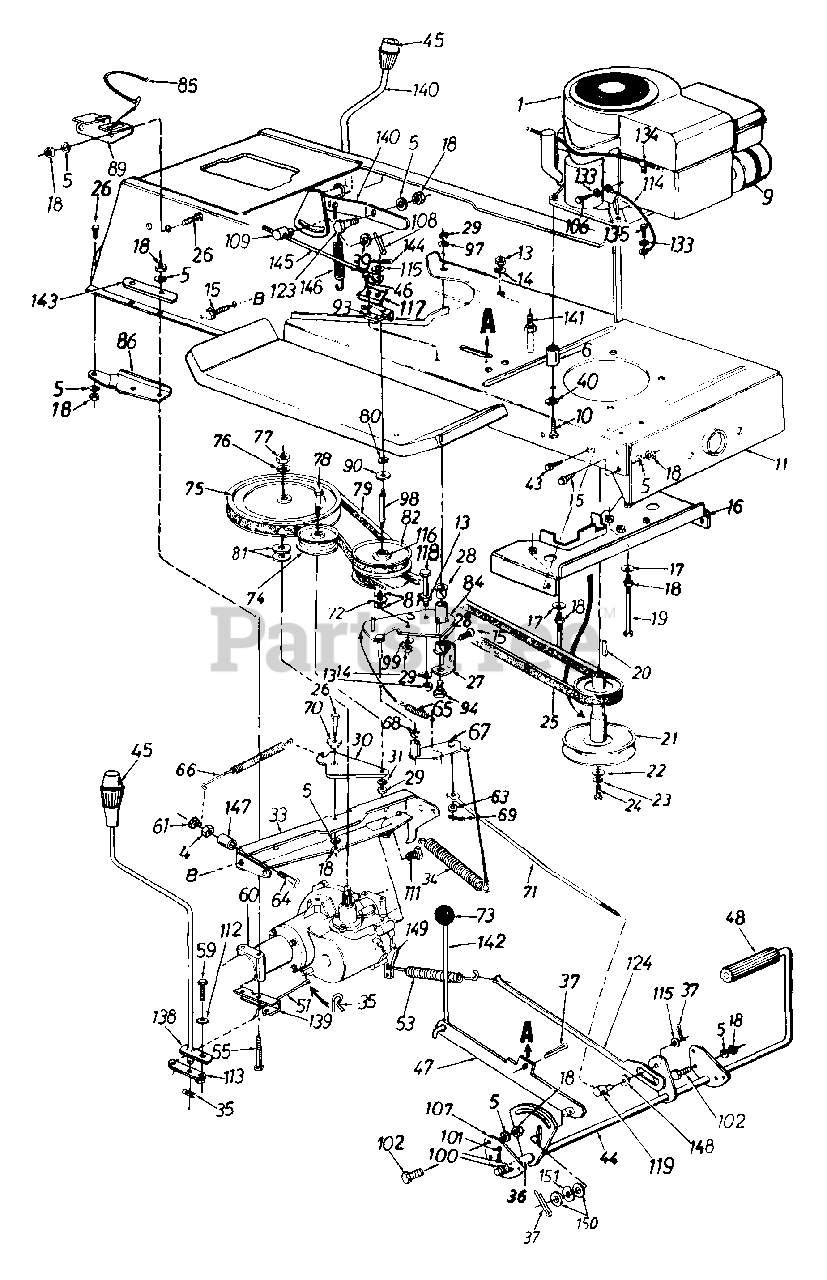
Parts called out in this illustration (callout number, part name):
1	Engine
4	Hex Nut 5/16-24 Thd.
5	L-Wash. 5 16" I.D.
6	Spacer
9	Muffler
10	Hex L-Wash. Tap Scr. 3/8-16 Thd.
11	Lower Frame Ass'y.
13	Hex Nut 1/4-20 Thd.
14	L-Wash. 1/4" I.D.
15	Hex Wash. TT-Tap Scr. 5/16-18 x .62" Lg.
16	Belt Guard Brkt. Ass'y.
17	Bell-Wash..345" I.D. x .88"
18	Hex Nut 5/16-18 Thd.
19	Hex Bolt 5 16-18 x 4.0"
20	Sq. Key 1/4" x 1/4" x 2.00"
21	Engine Pulley
22	Fl-Wash. 7/16" I.D. x 1.25"
23	L-Wash. 1/16" I.D.
24	Hex Bolt 7/16-20 x 1.50" Lg.
25	Variable-Speed Belt
26	Hex Bolt 5/16-18 x .75" Lg.
27	Bearing Shaft Bracket
28	Flanged Nyliner Brg..63" I.D. x .6" Lg.
29	Hex Nut 3/8-24 Thd.
30	Idler Bracket
31	L-Wash. 3/8" I.D.
33	Transaxle Support Brkt.
34	Ext. Spring .94" O.D. x 7.58"
35	Inter. Cotter Pin
36	Spacer .63" I.D.
37	Cotter Pin 1/8" Dia. x 1.25" Lg.
39	Fl-Wash..51" I.D. x .75"
40	Fl-Wash..406" I.D. x 1.25"
43	Hex Wash. Hd. S-Tap Scr. 1/4-20 x .50" Lg.
44	Clutch/Brake Pedal Ass'y.
45	Shift Knob
46	Truss Mach. B-lap Scr. #10 x .5" Lg,
47	Parking Brake Lockout Brkt. Ass'y.
48	Foot Pad
51	Shift Lever Rod
53	Ext. Spring 3.6"
55	Hex Bolt 5/16-18 x 3.25"
59	Hex Bolt 1/4-28 x .62" Lg.
60	Transaxle Complete
61	Hex L-Nut 1/4-20 Thd.
63	Fl-Wash..34" I.D. x .68" O.D.
64	Hex Wash. TT-Tap Scr. 1/4-20 x 1.75"
65	Ext. Spring 2.59" Lg.
66	Ext. Spring .5" O.D. x 4.35"
68	Flanged Bearing
69	Cotter Pin 3/32" Dia.
70	Shoulder Spacer .27" Lg.
71	Speed Control Link
72	Truss Bearing .56 Dia. x 1.25"
73	Ball Knob
74	Fl-Idler Pulley 3.25" x .75"
75	"V"-Pulley
76	Bell-Wash..567" I.D. x 1.125"
77	Hex Jam Nut 9/16-18 Thd.
78	Hex Bolt 3/8-24 x 1.75" Lg.
79	Variable Speed Belt
80	Snap Ring .56" Dia.
81	Fl-Wash..56" I.D. x 1.0" O.D.
82	Variable Speed Pulley Ass'y. 5" O.D.
90	Teflon Washer .565" I.D.
93	Safety Switch (Clutch)
94	Shld. Bolt 3/8-24 x 3.12" Lg.
97	Bell-Wash..38" I.D. x .88"
98	Shaft
99	Bell-Wash..39" I.D. x 1.12"
100	Fl-Wash..64" I.D. x .94"
101	Cotter Pin 1/8" Dia. x 1.25"
102	Hex Wash. Hd. Scr. 5/16-18 x .62" Lg.
106	Truss Mach. Scr. 5/16-18 x .75" Lg.
109	Ferrule
111	Hex Wash. Tap Scr.
112	Bell-Wash..265" I.D. x .75"
113	Shift Lever Link Ass'y.
114	Ground Wire 7.5" Lg.
115	Fl-Wash..385" I.D. x .62"
116	Needle Brgs.
117	Switch Plate
118	Hex Bolt 1/4-20 x 3.25" Lg.
119	Ferrule
123	Shld. Bolt .437" Dia. x .162"
124	Brake Rod Ass'y.
133	External L-Wash. 5/16" I.D.
134	Speed Clip
135	Hex Wash. AB-Tap Scr. 5/16" x .75" Lg.
138	Shift Lever Ass'y.
139	Shift Lever Support Brkt.
140	Speed Selector Lever Ass'y.
141	Belt Guard Pin
142	Brake Lockout Rod
144	Cotter Pin 1/8" x 3/4" Lg.
145	Speed Selector Rod
146	Ext. Spring 3.97" Lg.
147	Spacer.326" I.D. x .47"
148	Fl-Wash. 5/8" I.D. x 1.25"
149	Actuating Arm
150	Fl-Wash. .385" I.D. x .87" O.D.
151	Wave Wash. .38" I.D. x.75"
